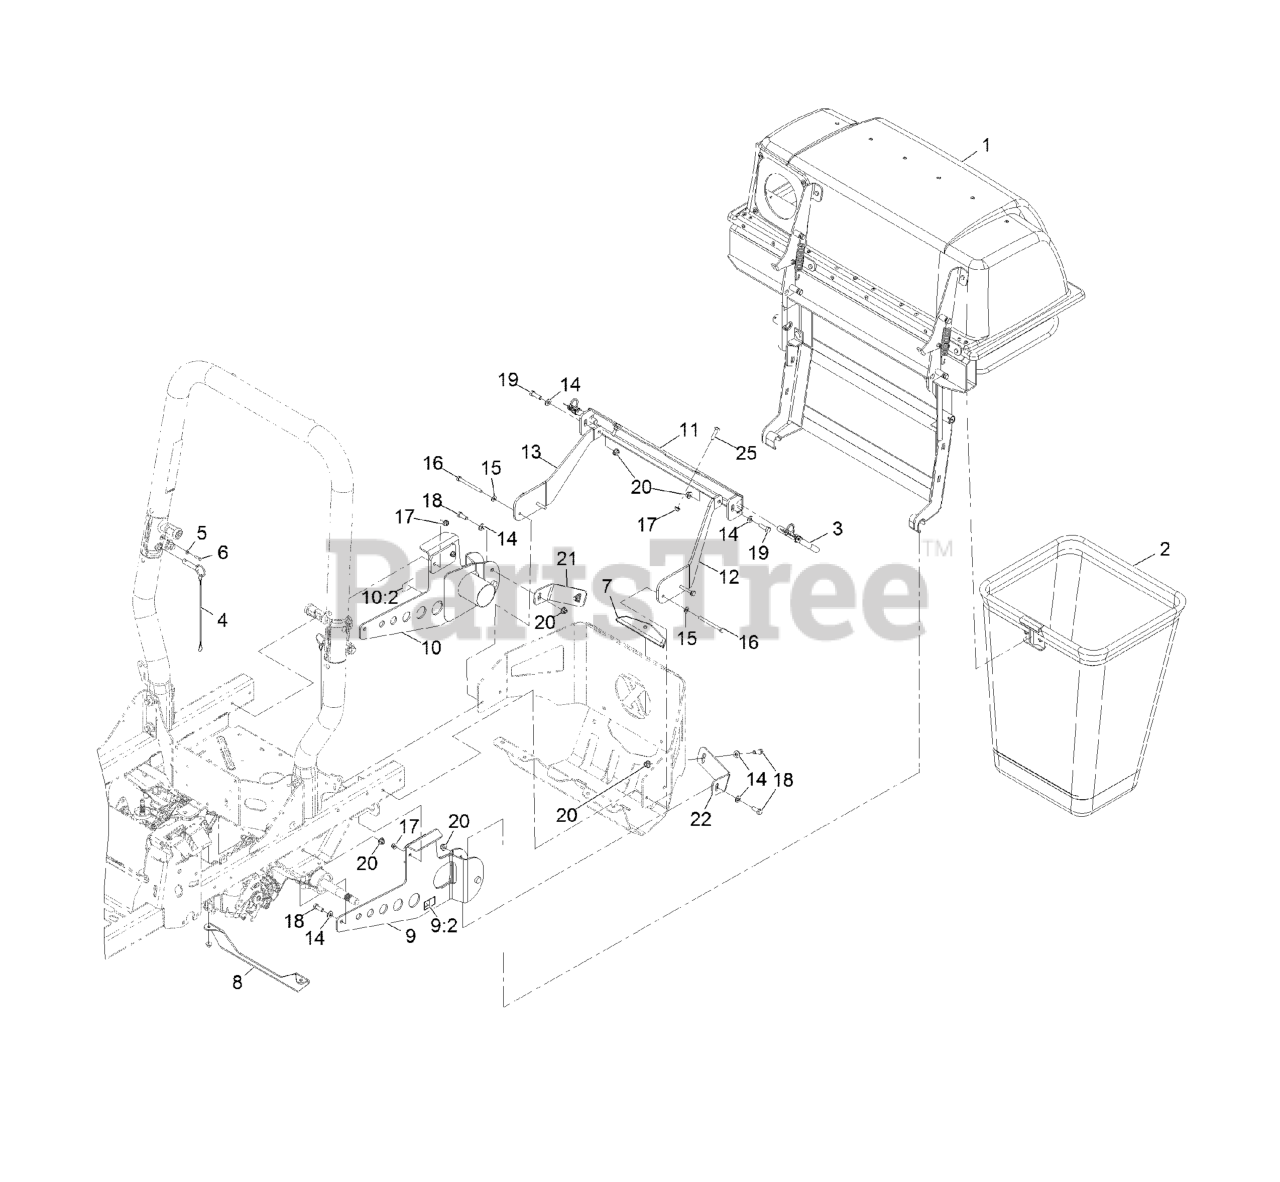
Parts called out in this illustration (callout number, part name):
1	Asm, Hood & Frame
2	BAG AND FRAME ASM
3	PIN-MOUNT, BAGGER
4	HITCH PIN ASM
5	WASHER-FLAT
7	COVER-HITCH
8	SUPPORT-TRANSMISSION
9	SUPPORT-BAGGER, LOWER LH
9:2	DECAL-WARNING
10	SUPPORT-BAGGER, LOWER RH
10:2	DECAL-WARNING
11	MOUNT-BAGGER LWR
12	BRACKET-UPPER, LH
13	BRACKET-UPPER, RH
14	WASHER-FLAT
15	WASHER-PLAIN
17	NUT-HF, NI
18	SCREW-HH
19	SCREW-HH
20	NUT-HF, NI
21	BRACKET-BAGGER, RH
22	BRACKET-BAGGER, LH
25	SCREW-HH
